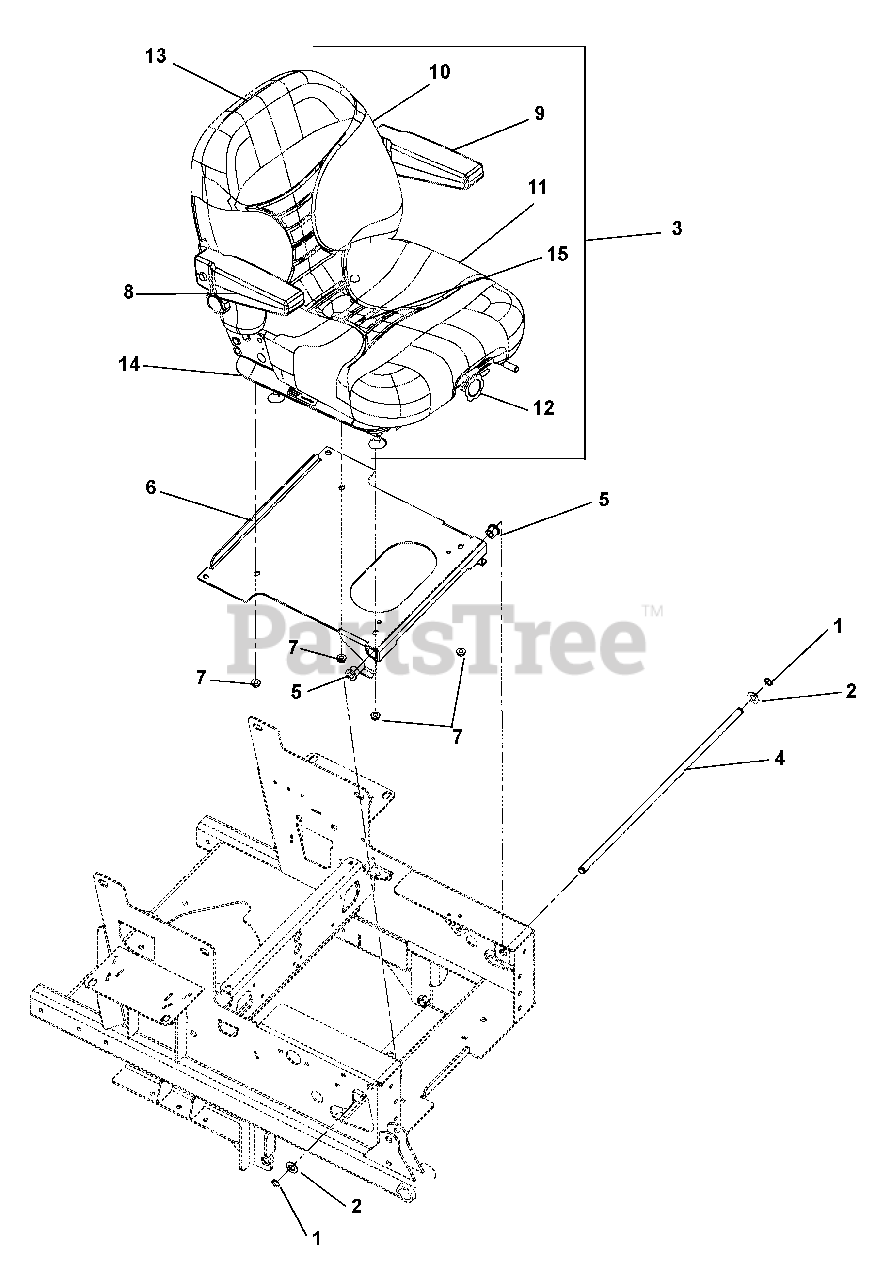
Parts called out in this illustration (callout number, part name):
1	RG-RTNG-EXT .500X.050 (SNAP)
2	WSHR-FL-STL.531X1.00X.063 YWZC
3	SEAT-SUSP-LT GRY-SEAT BLT BUSH
4	SHAFT, PT100 SEAT PIVOT
5	BSHG, FLG .516X.750X.625X.937
6	100I SEAT PLATE WMT - BLACK
7	NUT-LK-TOP-FLG .31-18 YWZC
8	KIT-RH ARMREST ASSEMBLY REPLAC
9	KIT-LH ARMREST ASSEMBLY REPLAC
10	KIT-BACK CUSHION-LIGHT GRAY
11	KIT-SEAT CUSHION-LIGHT GRAY
12	KIT-SEAT KNOB
13	KIT-SEAT BACK PANEL
14	KIT-SEAT SLIDE
15	KIT-SPRING AND SADDLE
